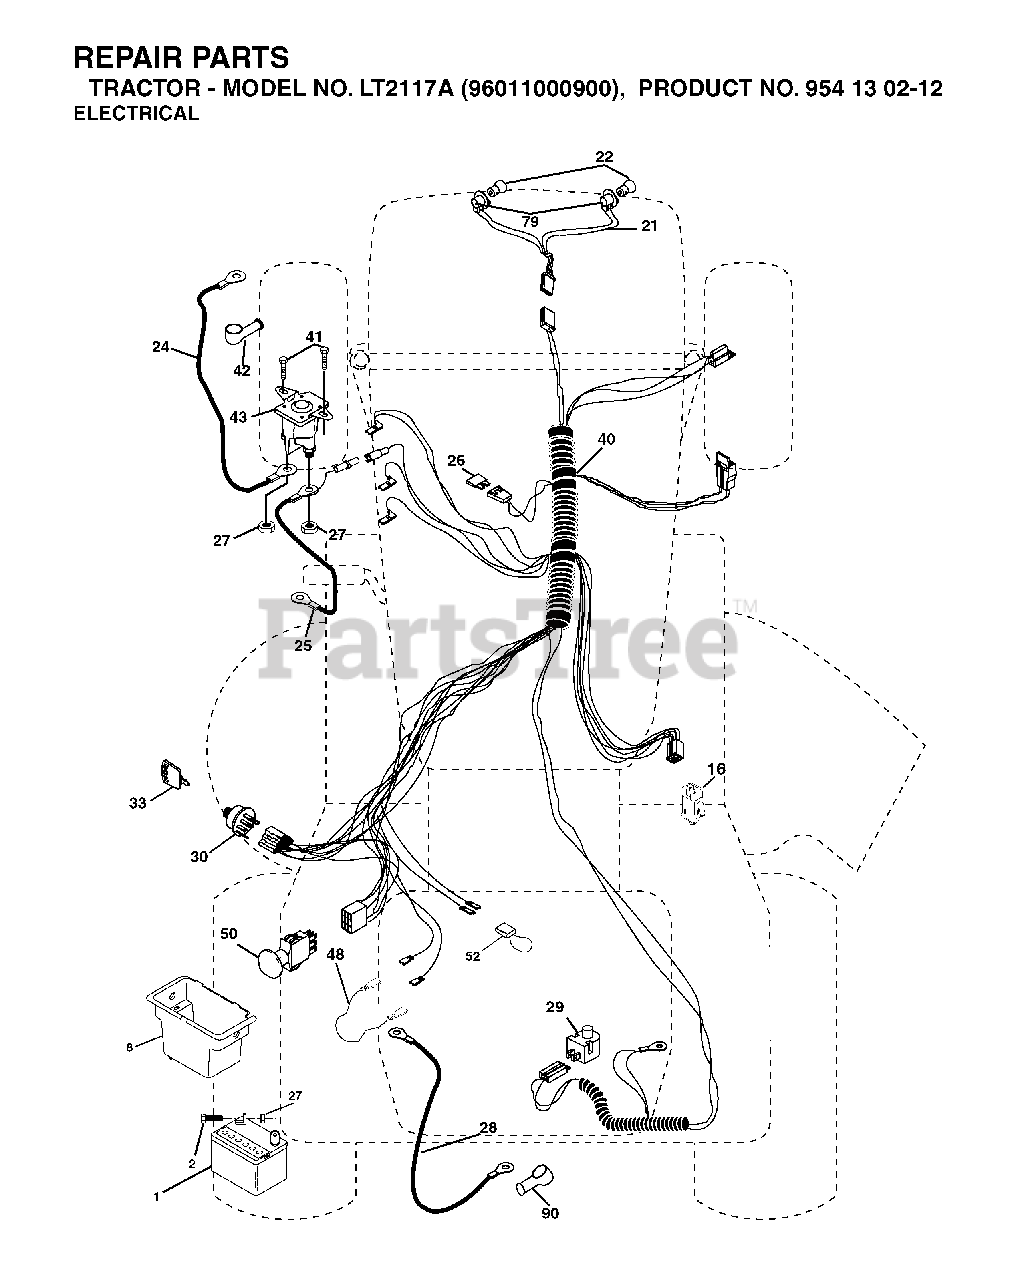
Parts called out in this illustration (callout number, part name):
1	BATTERY 12V .35 AMP
8	BOX.BATTERY.FENDER
16	SWITCH INTERLOOK PUSH-IN
21	HARNESS.W/LIGHT SOCKET
22	LIGHTBULB
24	BATTERY CABLE GT
25	CABLE BATTERY
26	FUSE 20AMP
27	NUT
28	CABLE T
29	SWITCH SEAT
30	IGNITION SWITCH
33	KEY MLD GEN DELTA
41	SCREW
42	TERMINAL COVER
43	SOLENOID
50	PTO SWITCH
52	WIRE PROTECTION LOOP
79	BULB HOLDER ASM.
81	RELAY.ASSY.T
90	COVER TERMINAL
